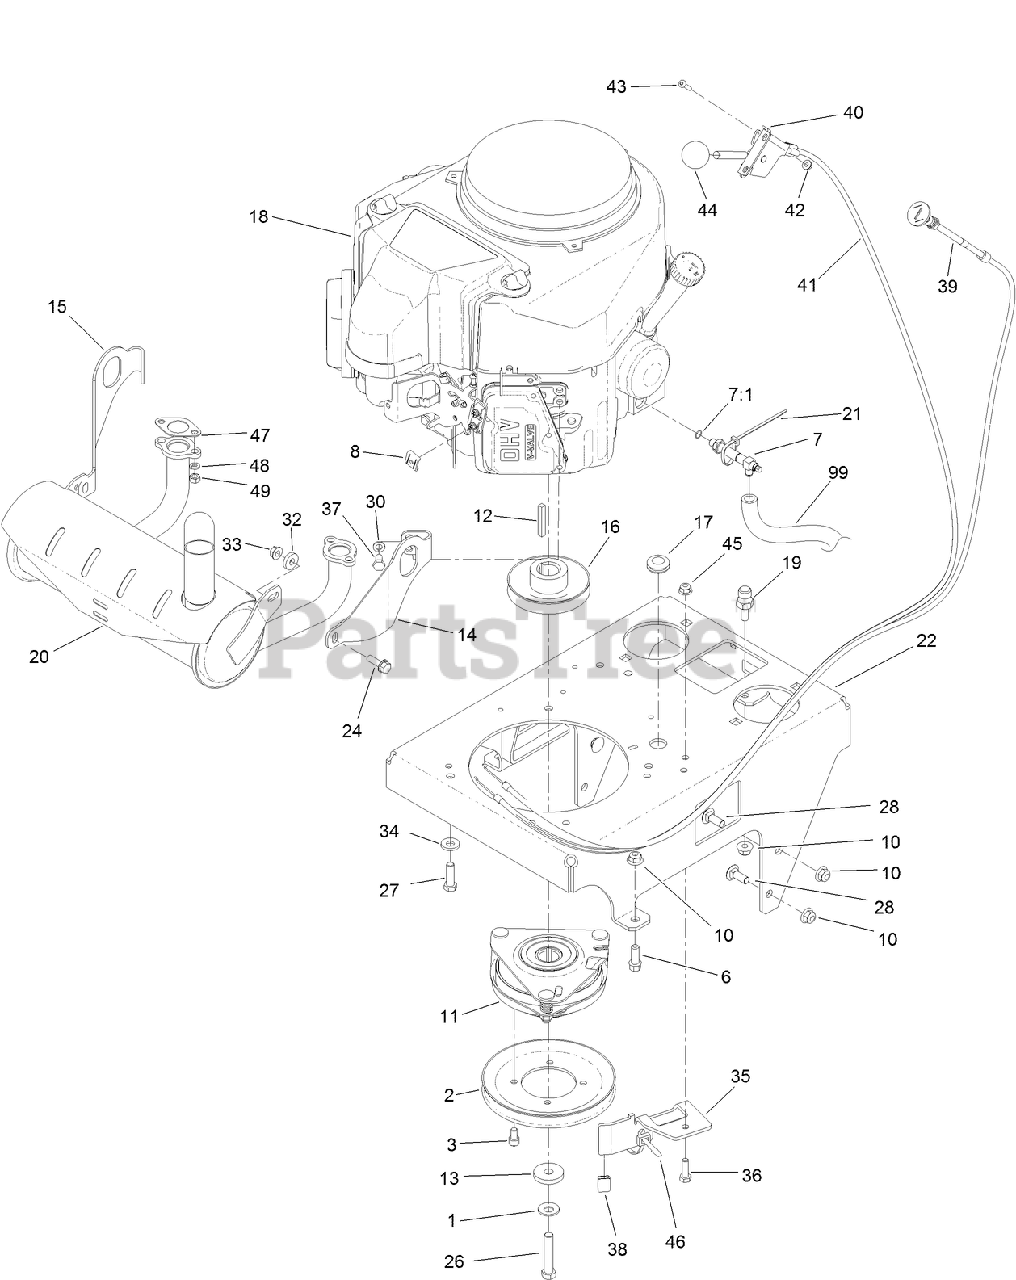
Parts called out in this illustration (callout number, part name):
1	WASHER-SPRING
2	PULLEY
3	SCREW-HSH
7	DRAIN-OIL, VALVE, KAW
7:1	O-RING
8	CLAMP-CABLE
10	NUT-HF, NI
11	CLUTCH/BRAKE ASM
12	KEY-SQUARE
13	WASHER
14	BRACKET-MUFFLER, LH
15	BRACKET-MUFFLER, RH
16	PULLEY
17	GROMMET
19	ANCHOR-SPRING, SHORT
20	MUFFLER
21	TIE-CABLE
22	BASE-ENGINE
24	SCREW-HHF
27	SCREW-HH
28	SCREW-HH
30	SCREW-HH
32	SPACER
33	NUT-HF
34	WASHER-BELLEVILLE
35	BRACKET-CLUTCH STOP
36	SCREW-HH
37	SCREW-HH
38	BUMPER
39	CONTROL-CHOKE, PUSH / PULL
40	LEVER-CONTROL
41	CABLE-CONTROL
42	NUT-LOCK, FLANGE
43	BOLT-CARR
44	KNOB-BALL
45	NUT-HF, NI
46	TIE-CABLE
47	GASKET-EXHAUST
48	WASHER-LOCK
99	HOSE-DRAIN, OIL
